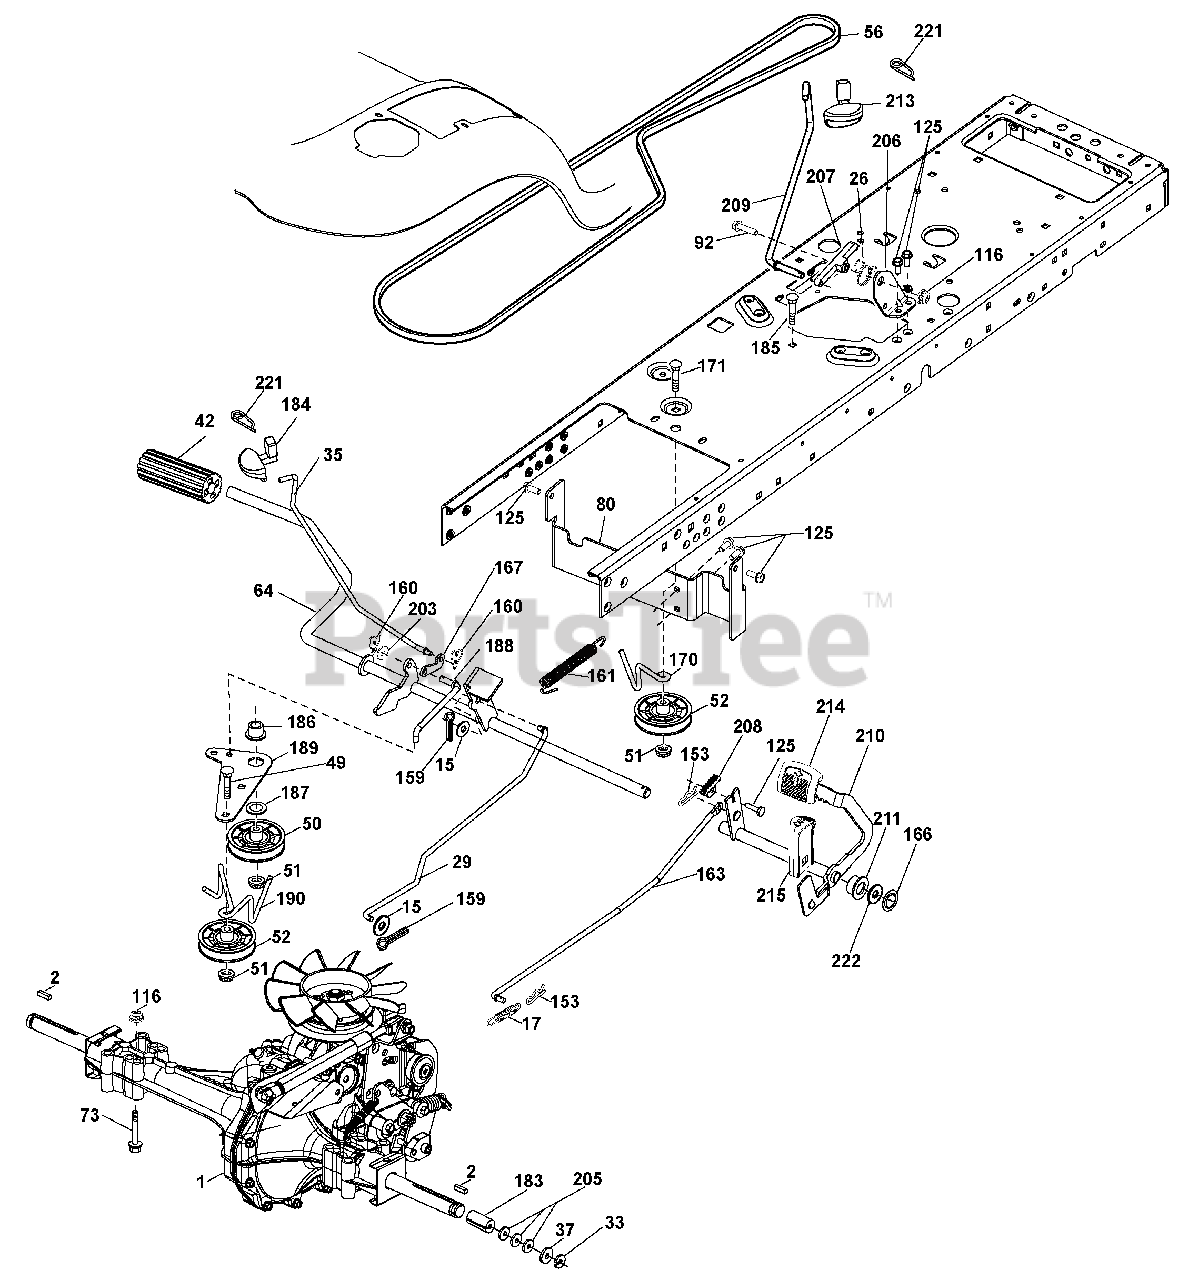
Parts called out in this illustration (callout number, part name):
2	Key
15	Washer 13/32 x 13/16 x 16 Ga.
17	Spring, Brake
26	Spring Return Cruise
29	Rod, Brake
33	Ring E #5133-75
35	Rod, Brake, Park
37	Washer 25/32 x 1-1/4 x 16 Ga.
42	Cover, Foot Pedal
49	Bolt
50	Pulley Idler Flat
51	Lock Nut 3/8-16
52	Idler V-Groove 910" Offset
56	V-Belt, Drive
64	Shaft Asm. Pedal Brake Control
73	Bolt Hex Flgnd 5/16-18 Gr 5
80	Bracket Strp. Trq.
92	Bolt Fin Hex 5/16-18 unc x 1.25
116	Nut Lock Hex Flange 5/16-18
125	Screw 5/16-18 x 3/4
153	Retainer Spring 1"
159	Pin Cotter 1/8 x 3/4
160	Retainer Clip
161	Spring, Return, Clutch
163	Rod Pedal Control
166	Nut Push .625
167	Latch Brake Parking
170	Keeper Belt Centerspan
171	Bolt
183	Spacer
184	Handle Parking Brake
185	Bolt
186	Spacer Retainer
187	Washer
188	Link Clutch Ground Drive
189	Bellcrank Ground Drive
190	Keeper Bellcrank Ground Drive
203	Washer 11/32 x 11/16 x 16 Ga.
205	Washer 25/32 x 1-5/8 x 16 Ga.
206	Bracket Mount Latch Cruise
207	Latch Control Cruise
208	Gear Sector Control Cruise
209	Rod Control Cruise
210	Rocker Asm. Pedal Control
211	Bearing Nylon Blk .629
213	Knob Control Cruise
214	Pedal Forward
215	Pedal Reverse
221	Retainer Spring Clip Handle
222	Washer 21/32 x 1-1/4 x 10 Ga.
